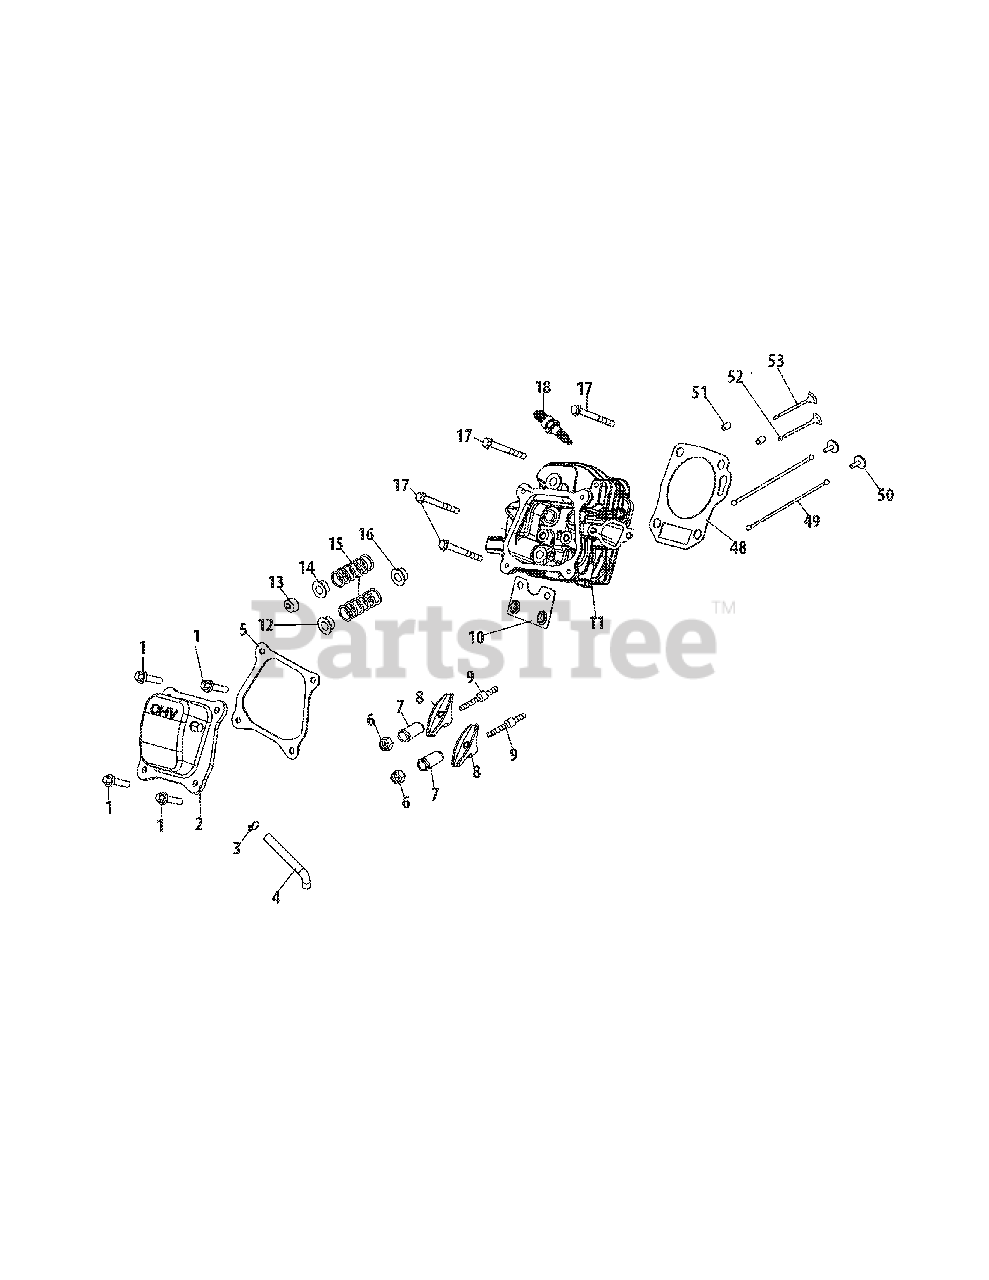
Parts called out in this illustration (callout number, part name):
1	BOLT M6×16
2	CYLINDER HEAD COVER
3	CLAMP, FUEL HOSE
4	VENTING HOUSE
5	GASKET, VALVE COVER
6	LOCK NUT
8	ROCKER ARM
9	ROCKER ARM STUD
10	ROCKER ARM BASE
11	CYLINDER HEAD
12	INTAKE VALVE SPRING SEAT
13	ROTATOR, EXHAUST VALVE
14	EXHAUST VALVE SPRING SEAT
15	SPRING VALVE
16	INTAKE VALVE SEAL
17	BOLT M8×55
18	SPARK PLUG(F6RTC)
48	GASKET,CYLINDER HEAD
49	PUSH ROD
50	TAPPET
51	DOWEL PIN 10×16
52	VALVE INTAKE
53	EXHAUST VAVLE
